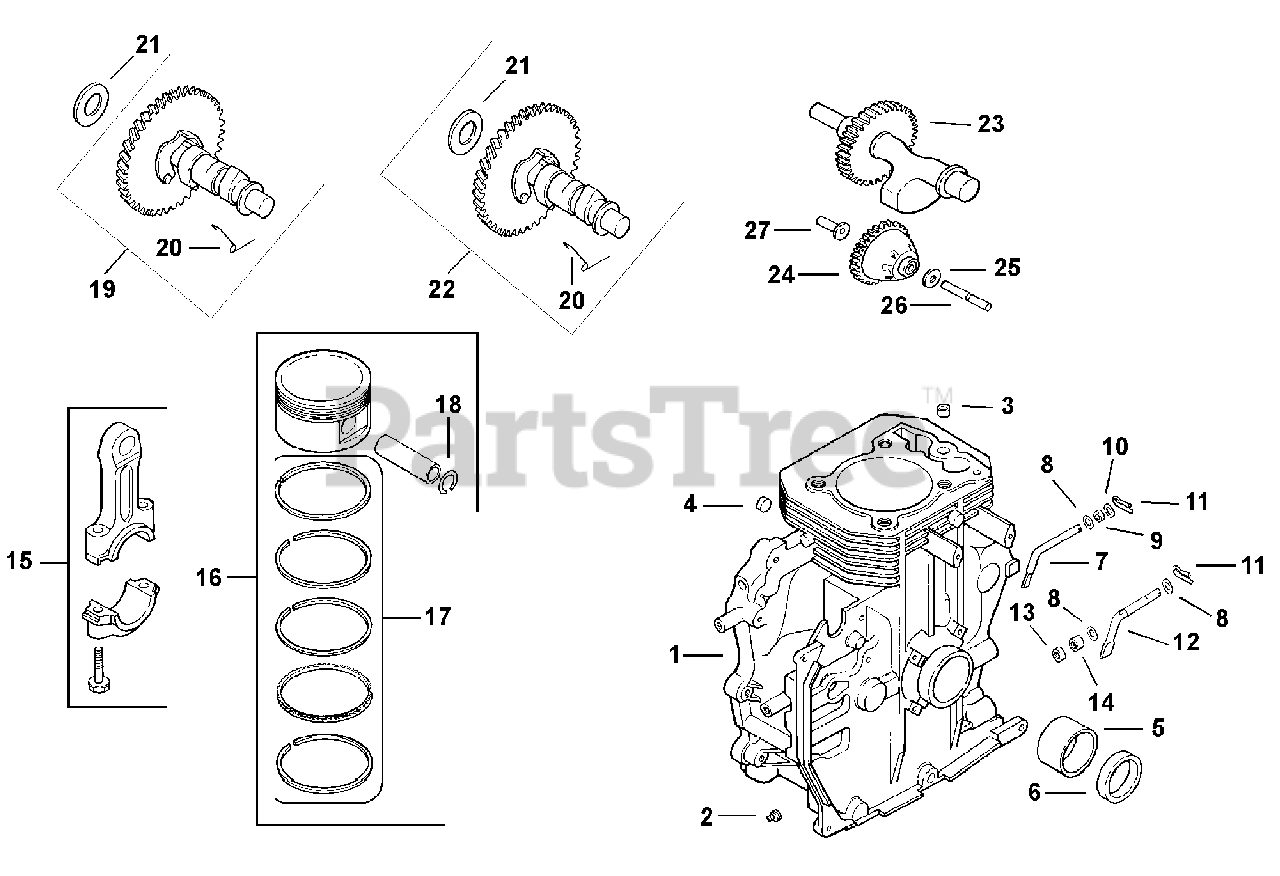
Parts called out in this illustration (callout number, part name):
1	Crankcase
2	PLUG, SQ HD PIPE 3/8" USE 25 139 57-S
3	PIN - USE 12 380 17
4	PLUG, CUP
5	BEARING .25mm
5	BEARING .50mm
6	SEAL, OIL
8	Washer, plain 6 mm
12	SHAFT, GOVERNOR CROSS
15	ROD - USE 12 067 05
15	ROD - USE 12 067 06
16	KIT, PISTON W/RING SET (STD) - DISCONTINUED
16	KIT, PISTON W/RING SET (.25) - DISCONTINUED
16	KIT, PISTON W/RING SET (.50)
17	RING SET (STD.)
17	RING SET (.25)
17	RING SET (.50)
20	SPRING - USE 12 089 31
21	SHIM, CAMSHAFT (BLUE .03")
21	SHIM, CAMSHAFT (RED .032")
21	SHIM, CAMSHAFT (YELLOW .034")
21	SHIM, CAMSHAFT (GREEN .036")
21	SHIM, CAMSHAFT (GRAY .038")
21	SHIM, CAMSHAFT (BLACK .04")
21	SHIM, CAMSHAFT (WHITE .028")
22	KIT, CAMSHAFT
23	SHAFT - USE 12 144 21
24	GOVERNOR GEAR ASSEMBLY
25	Washer, plain 6 mm
26	SHAFT, GOVERNOR GEAR
27	PIN, GOVERNOR REGULATING
